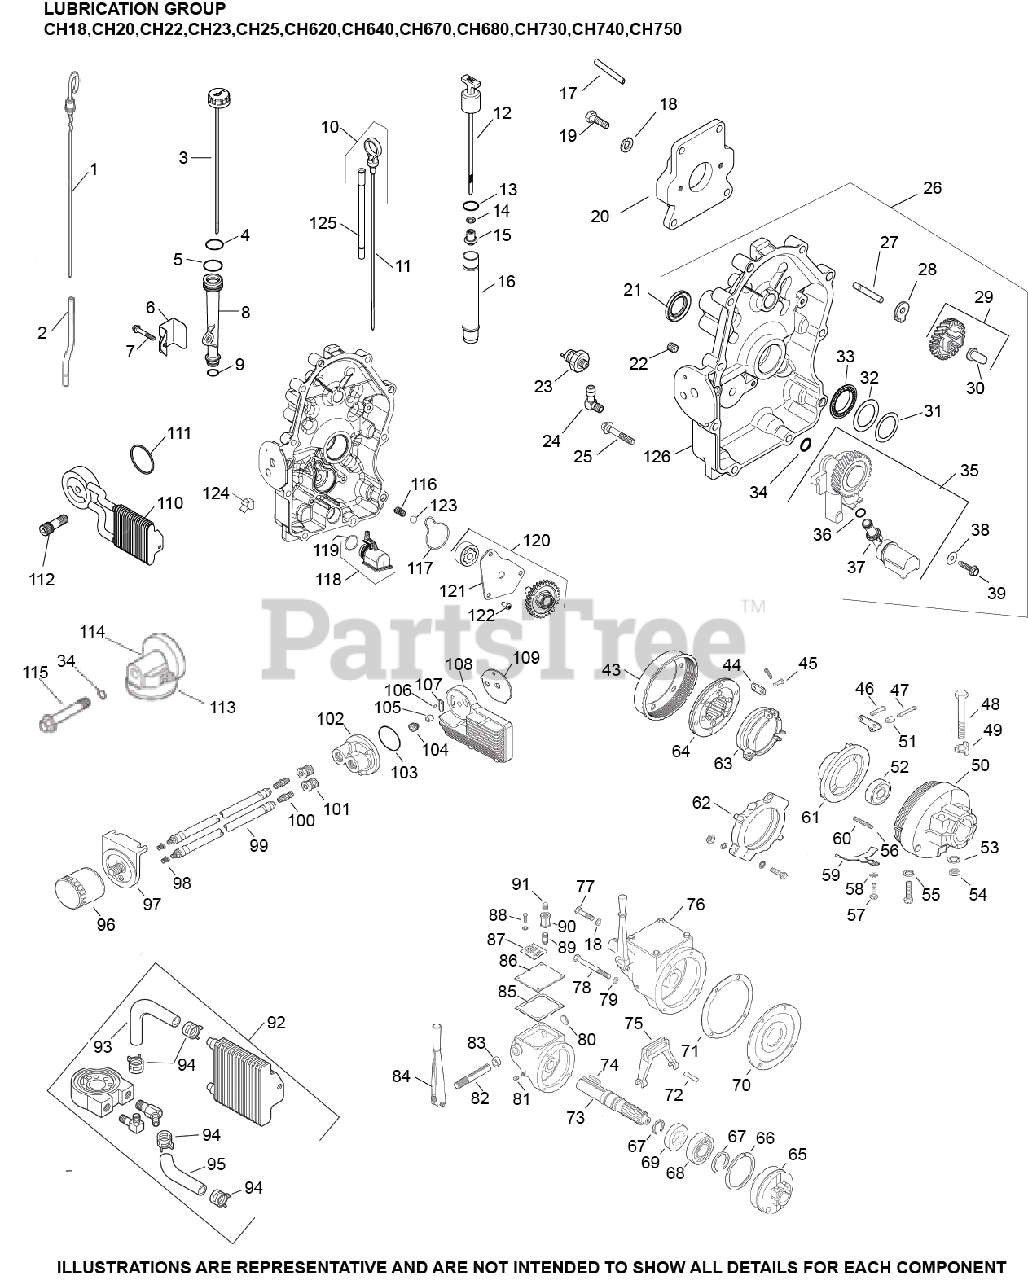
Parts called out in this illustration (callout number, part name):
1	CLOSURE PLATE ASSEMBLY USE 24 009 237-S
7	SCREW, FLG M8X1.25X50
10	KIT, DIPSTICK/DIPSTICK TUBES
21	SEAL, OIL
22	PLUG, CTSK PIPE 1/8"
23	SENSOR, OIL PSI
25	SCREW, FLG M8X1.25X45
25	SCREW - DISCONTINUED
27	SHAFT, GOVERNOR GEAR
28	TAB, LOCKING
29	KIT, GOVERNOR GEAR W/PIN
30	PIN, GOVERNOR REGULATING
35	PUMP ASSEMBLY, OIL-USE 24 393 53-S
36	O-RING, OIL PICK-UP
37	PICK-UP, OIL
38	WASHER, FLAT 6 MM
39	SCREW,FLG THD FRM M6X1.0X25-(#25086395S)
96	OIL FILTER
112	NIPPLE, OIL FILTER
116	SPRING, COMPRESSION
117	SEAL, OIL PUMP COVER
118	PICK-UP ASSEMBLY, OIL
119	O-RING, OIL PICK-UP
120	PUMP ASSEMBLY, OIL
121	COVER, OIL PUMP
122	SCREW, BUTTON HEAD
123	PRESSURE RELIEF BALL
